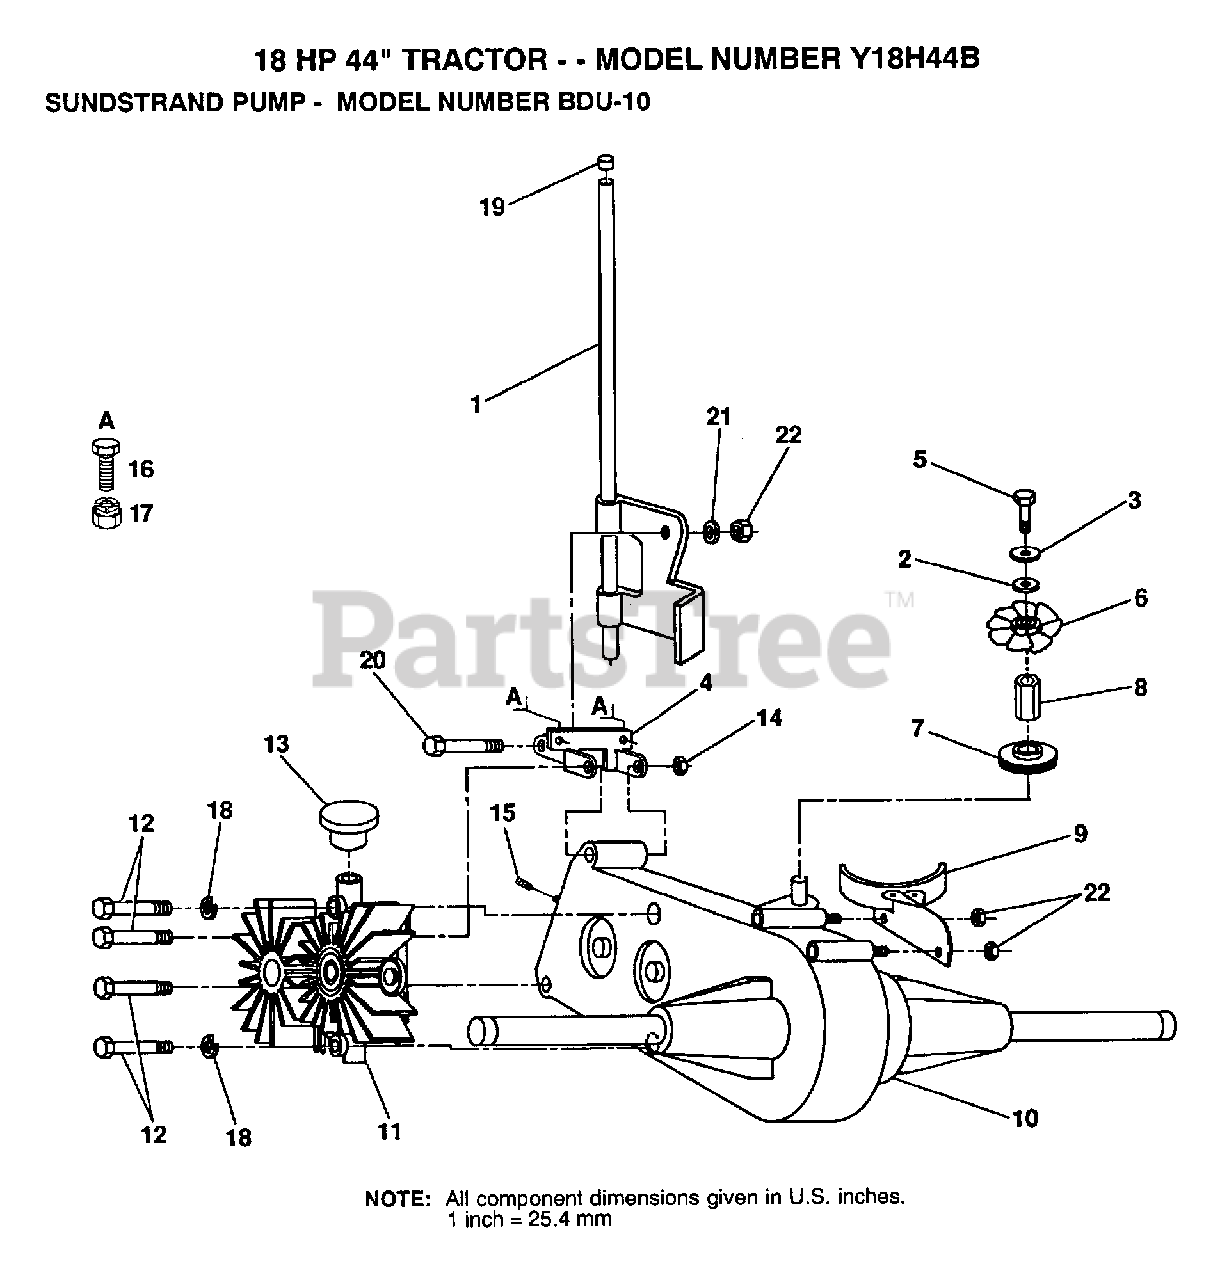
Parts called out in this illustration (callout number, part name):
1	CONTROL ASSY
2	WASHER
3	LOCKWASHER
4	BRACKET
6	FAN
7	PULLEY TRANSAXLE
8	STANDOFF
9	GUARD ASSY
10	TRANSAXLE.AGRIFAB
11	PUMP.BDU-10S-114
12	BOLT YT
13	PUMP.2003081.
15	SPRING
18	LOCKWASHER
19	PLUNGER CAP T
20	BOLT T
21	WASHER T
